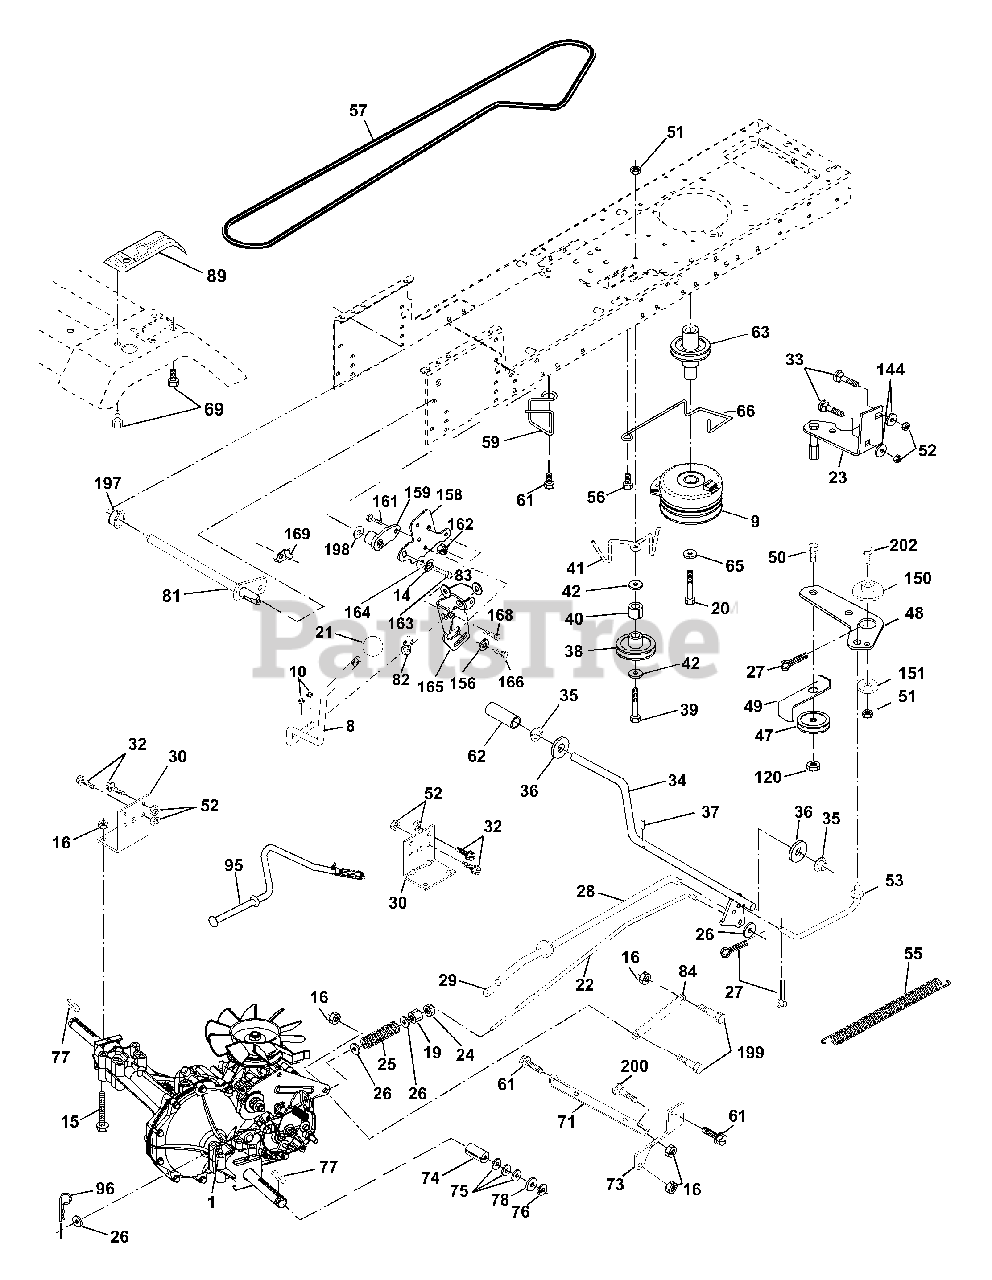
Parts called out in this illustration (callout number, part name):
8	Rod Shift Fender Adjust LT
9	Clutch Elecric
10	Pin Cotter 1/8 x 1 CAD
14	Washer Lock Hvy Helical
15	Bolt Hex 5/16-18 Gr. 5
16	Nut Lock Hex W/Ins. 5/16-18 Unc P
19	Nut Lock Hex W/Ins 3/8-16 Unc
20	Bolt, Hex 7/16-20 x 4-1/4 Ga. 5
21	Knob Deluxe 1/2-13 UNC BLK/BLK
22	Rod, Brake Hydro
23	Bracket Asm. Anti-Rot EVX
24	Nut Hex Jam 3/8-16 UNC
25	Spring, Brake Rod
26	Washer
27	Pin Cotter 1/8 x 3/4 CAD.
28	Rod, Parking Brake
29	Cap,Parking Brake
30	Bracket, Transaxle
32	Bolt Hex Hd 5/16-18 Unc x 3/4
33	Bolt Carriage 5/16-18 UNC x 3/4
34	Shaft, Foot Pedal
35	Bearing, Nylon
37	Pin, Roll
38	Pulley, Idler, Flat
39	Bolt
40	Spacer Split
41	Keeper, Belt Idler
42	Washer 13/32 x 13/16 x 12 Ga
47	Pulley, Idler, V-Groove Plastic
48	Bellcrank Clutch Grnd Drv Stl
49	Retainer, Belt Style Spring
50	Bolt Hex Hd 3/8-16 Unc x 1-1/2
52	Nut Crown Lock 5/16-18
53	Link, Clutch
55	Spring, Return, Clutch
56	Screw 3/8-16 x 1.0
57	V-Belt, Ground Drive
59	Keeper, Center Span
61	Screw 3/8-16 x 3/4
62	Cover, Pedal
63	Pulley, Engine
65	Washer Lock Hvy HLCL Spr 7/16
66	Keeper Belt Engine
69	Screw Hex Wsh Hi-Lo 1/4-1/2 Unc
71	Strap Torque Lh
73	Strap Torque Rh
74	Spacer, Axle
75	Washer 25/32 x 1-1/4 x 16 Ga.
77	Key, Square
78	Washer 25/32 x 1-5/8 x 16 Ga
81	Shaft Asm Cross Tapered
82	Spring Torsion
83	Washer 17/32 x 3/4 x 16 Ga.
84	Link Transaxle
89	Console, Hydro
95	Control Asm. Bypass Hydro
96	Retainer Spring 1" Zinc/Cad
120	Nut Lock Flg. 3/8-16
144	Washer 11/32 x 5/8 x 16 Ga.
150	Bushing Bellcrank Grd Drive
151	Washer 13/32 x 2 x 10 Ga.
156	Washer Srrted 5/16 ID X 1 X .125
158	Bracket Shift Mount
159	Hub Tapered Flange Shift LT
161	Bolt Rdhd Sqnk 1/4-20 x 3/4 Gr. 5
162	Nut Crownlock 1/4-20 Unc
163	Bolt Hex Fin 1/4-20 Unc x 1 Gr. 5
164	Washer 5/8 x .281 x 10 Ga.
165	Bracket Pivot Lever
166	Screw 5/16-18 x 5/8
168	Bolt Shoulder 5/16-18 x .561
169	Plate Fastening LT
197	Nyliner Snap-In 5/8" ID
198	Washer Nyl 7/8ID x .105 Hyd
199	Bolt Shoulder 5/16-18 Unc
200	Bolt Rdhd Sqnk 5/16-18 Unc x 1
